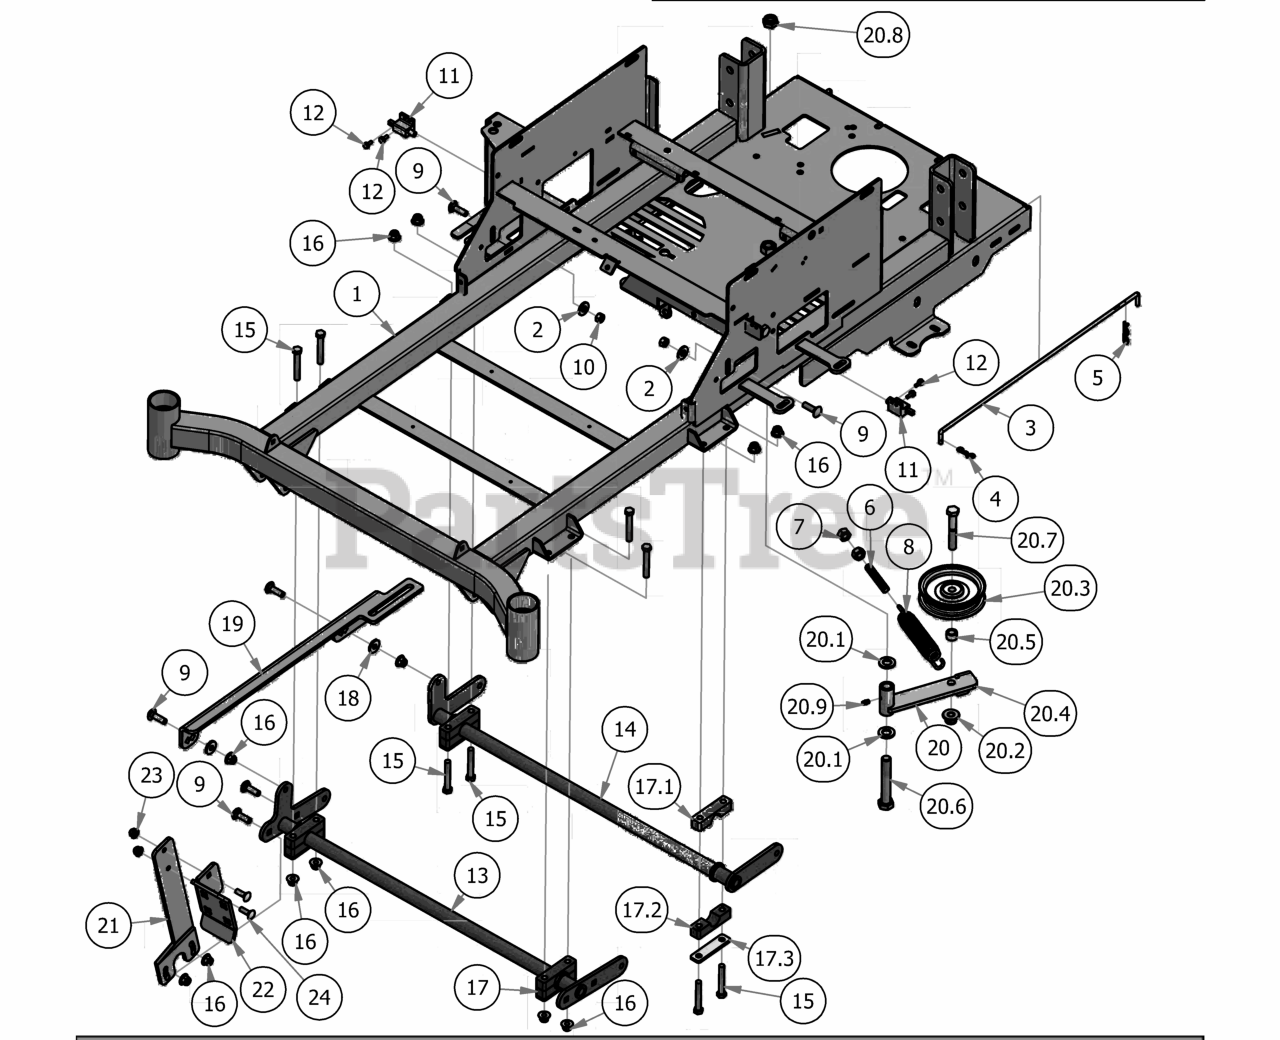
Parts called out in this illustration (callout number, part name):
1	2018 Compact Outlaw Frame
2	3/8" Flat Washer
3	ZT Neutral level rod 2011
5	Neutral Rod Clip
6	All Thread-Pump Idler Tensioner
7	1/2" Hex Nut
8	Deck Idler Spring
9	3/8" x 1 1/4" Carriage Bolt
10	3/8" Hex Nut
11	Safety Switch
12	12-24x 1/2 HWH Bolt
13	Actuator Bar Front- 2017 MZ/ZT
14	Actuator Bar Rear- 2017 MZ/ZT
15	3/8-16 x 2 1/2" Hex Bolt
16	3/8 Nylock Flange Nut
17	Pillow Block Kit
17.1	Pillow Block MZ Male
17.2	Pillow Block MZ Female
17.3	Pillow Block Strap
18	.360 ID Plastic Washer
19	2017 MZ/ZT Actuator Linkage
20	ZT Pump Idler
20.1	.630 ID Plastic Washer
20.2	1/2"-13 Nylon Flange Nut
20.3	4 3/4" Idler Pulley
20.4	Pump Idler Bracket
20.5	1/2" x 1/2" Spacer
20.6	5/8" x 4" Hex Bolt
20.7	1/2" x 2 3/4" Hex Bolt
20.8	5/8" Nylock (1/2" Jam)
20.9	1/4" Press in Grease Fitting
21	2017 MZ/ZT Deck Pedal Lever
22	2017 MZ/ZT Shallow Foot Pedal
23	5/16" Nylon Flange Nut
24	5/16" x 1" Carriage Bolt
